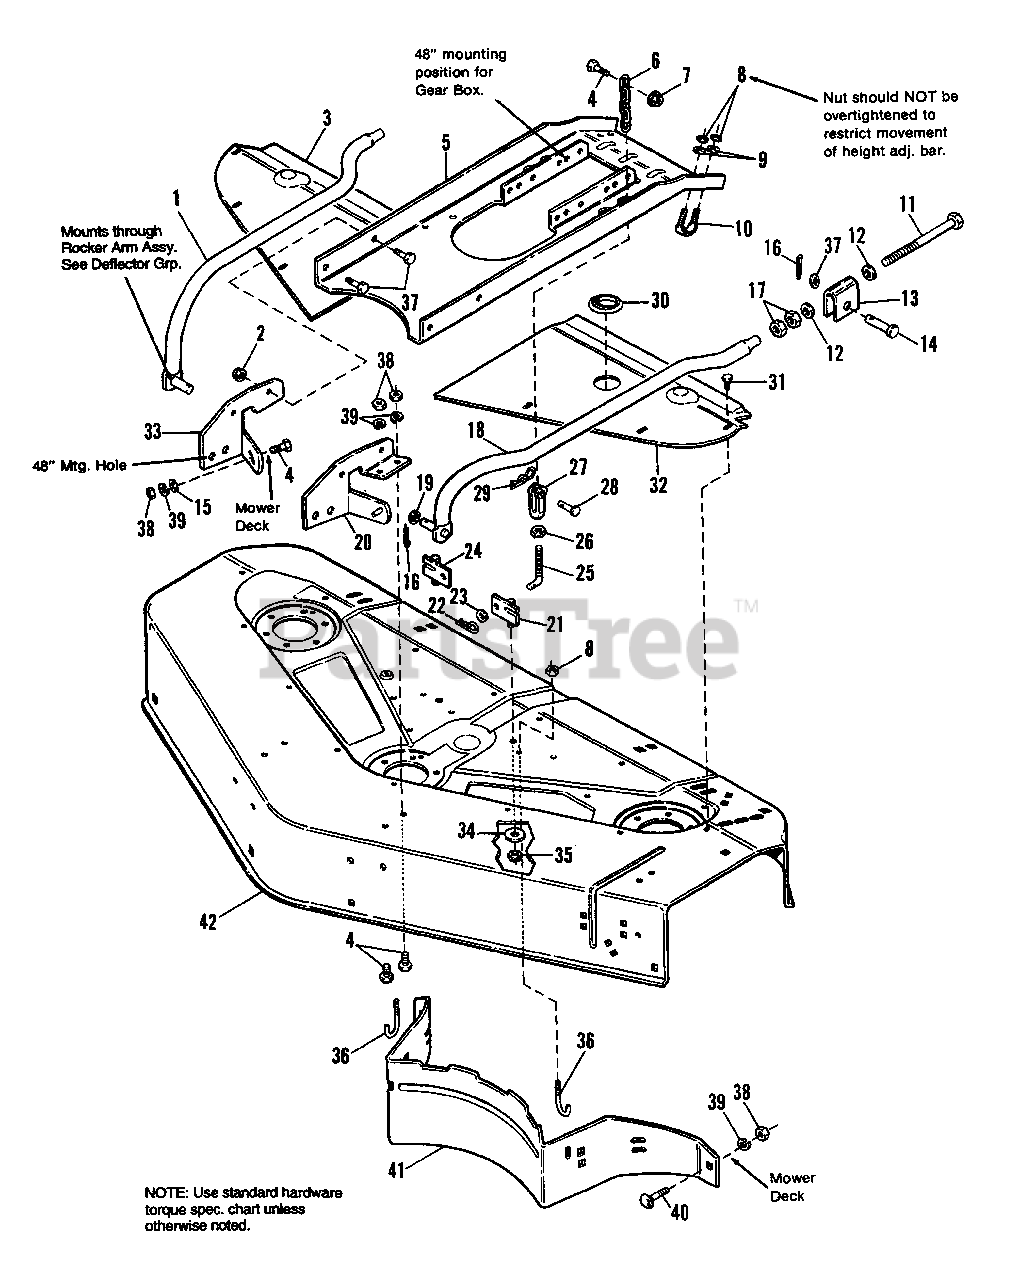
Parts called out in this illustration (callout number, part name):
1	ARM ASSY., R.H.
2	NUT, Hex Whizlock, 3/8-16
3	COVER, Mower, R.H.
4	CAPSCREW, Hex Hd., 3/8-16 x 1
5	SUPPORT, "U" Channel
6	CHAIN, 5 Link
6	CHAIN, 6 Link
7	NUT, Hex, Flange, Lock 3/8-16
8	NUT, Hex, Centerlock, 5/16-18
9	WASHER, 11/32
11	CAPSCREW, Hex, 5/8-18 x 5-1/2
12	WASHER, 5/8
13	TRUNNION
14	PIN, Trunnion
15	WASHER, 13/32
16	PIN, Cotter, 1/8 x 1
17	NUT, Hex, Jam, 5/8-18
18	ARM ASSY., L.H.
19	WASHER,21/32
20	BRACKET ASSY., L.H.
21	BRACKET ASSY., Lift, L.H.
22	PIN, Hair, 1/16" Wire
23	WASHER, Plain, 5/16 x 3/4 x 1/16
24	BRACKET ASSY., Lift, R.H.
26	NUT, Hex, Jam, 5/16-18
27	CLEVIS, Lift
28	PIN, Clevis
29	CLIP, Hair Pin
30	PLUG, Mower Cover
31	SCREW, Hex, Taptite, 1/4-20 x 3/8
32	COVER, Mower, L.H.
33	BRACKET ASSY., R.H.
34	WASHER, Plain, 13/32 x 1-1/2 x 1/8
35	NUT, Hex, Centerlock 3/8-16
36	SCREW, Baffle Hook
37	CAPSCREW, 3/8"
38	NUT, Hex, 3/8-16
39	LOCKWASHER, 3/8
40	BOLT, Carriage, 3/8-16 x 1
41	BAFFLE, Mower
42	HOUSING, 48" Mower
